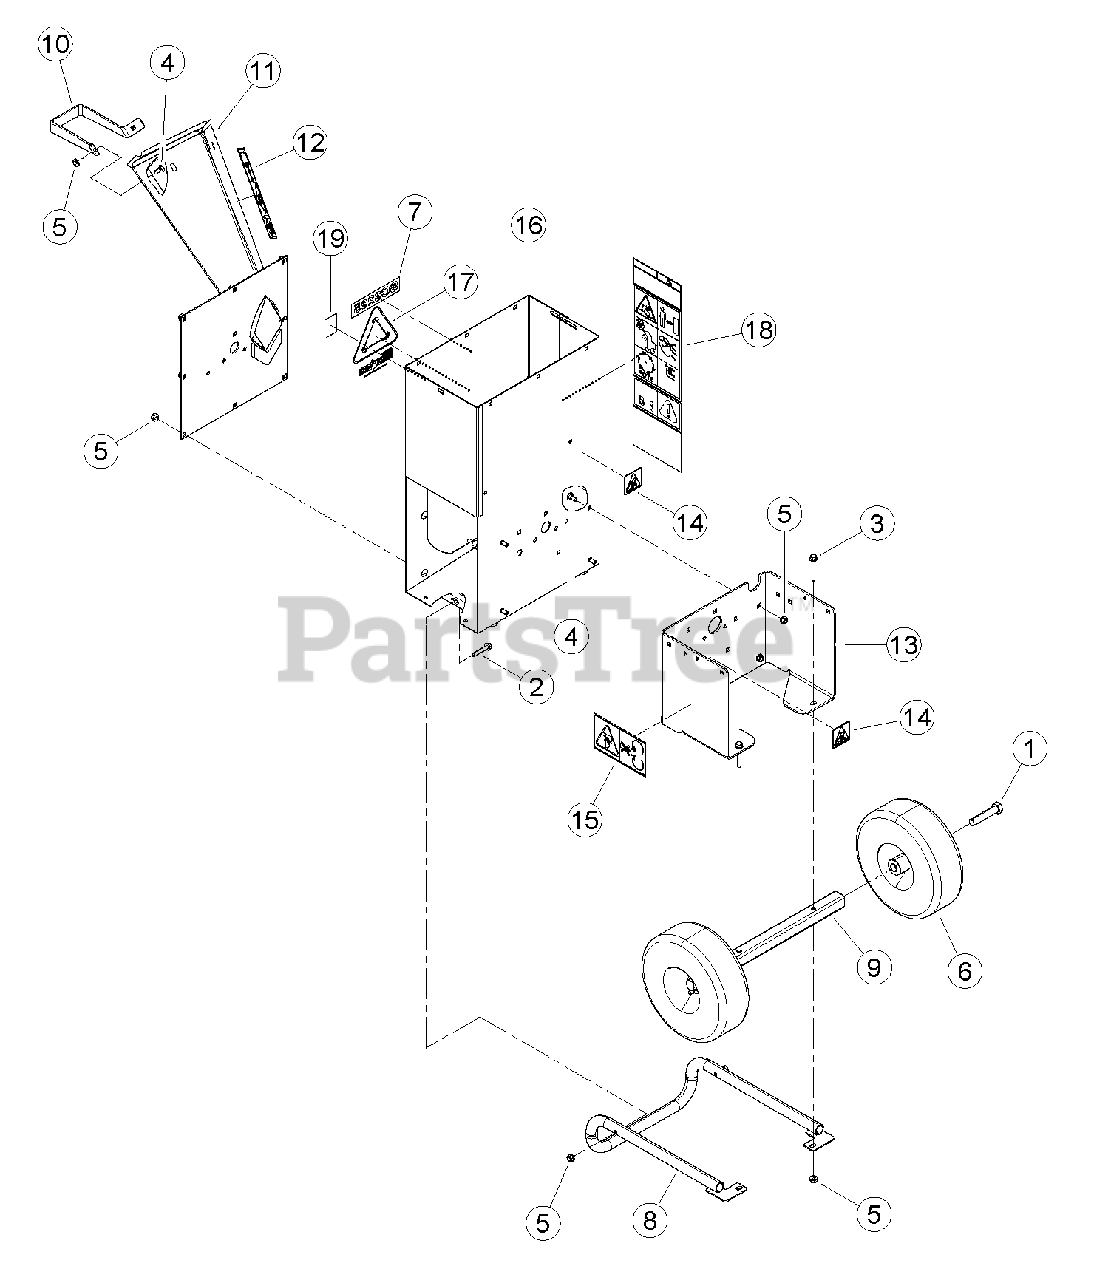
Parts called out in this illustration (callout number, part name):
1	BOLT, 5/8 X 3 HEX GR5 ZP
2	BOLT, 5/16 X 1-3/4 FLANGE NC
3	BOLT, 5/16 X 2-1/4 FLANGE NC
4	BOLT, 5/16 X 3/4 CRG GR5 NC ZP
5	NUT, 5/16-18 NYLOCK-FLANGE
6	ASSEMBLY, WHEEL 410/350-4
7	DECAL, MODEL SC3306
7	DECAL, MODEL SC3306E
8	WELDMENT, SUPPORT LEG LONG
9	WELDMENT, AXLE 3 IN CHIPPER
10	HANDLE, CHIPPER CHUTE 3 IN
11	ASSEMBLY, 3 IN FRONT PLATE COMP
12	DECAL, 3" CHIPPER CHUTE
13	ASSEMBLY, BASE 3 IN CHIPPER SERVICE PART
14	DECAL, SHIELD DANGER ISO
15	DECAL, BLADE DANGER ISO
16	ASSEMBLY, 3" C/S WIDE BODY SERVICE PART
17	DECAL, SHRED IT
18	DECAL, 3" CHIPPER BODY SIDE
19	DECAL, ECHO BEARCAT QR CODE
